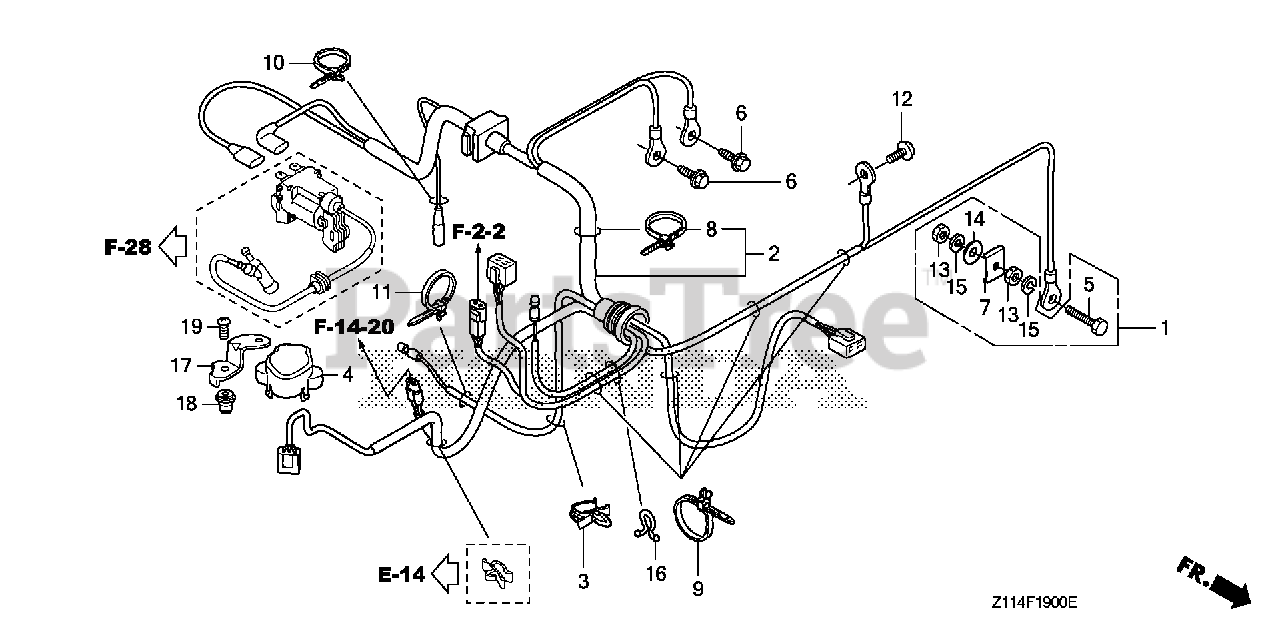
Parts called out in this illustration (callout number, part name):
1	TERMINAL SET, GROUND
2	WIRE HARNESS ASSY., ENGINE
3	CLIP B, HARNESS
4	COVER, THROTTLE MOTOR
5	BOLT, HEX. (6X28)
6	BOLT, FLANGE (6X12) (CT200)
7	RETAINER (6MM)
8	STRAP, CABLE (118MM) *NH1L* (Honda Code 1170653). (BLACK)
9	STRAP, CABLE (105MM) *NH1* (Honda Code 1685536). (BLACK)
10	BAND, CABLE
11	CLIP B, HARNESS BAND (129.4MM) (DARK BROWN)
12	SCREW, PAN (5X8)
13	NUT, HEX. (6MM)
14	WASHER, PLAIN (6MM)
15	WASHER, SPRING (6MM)
16	CLIP, TUBE (26)
